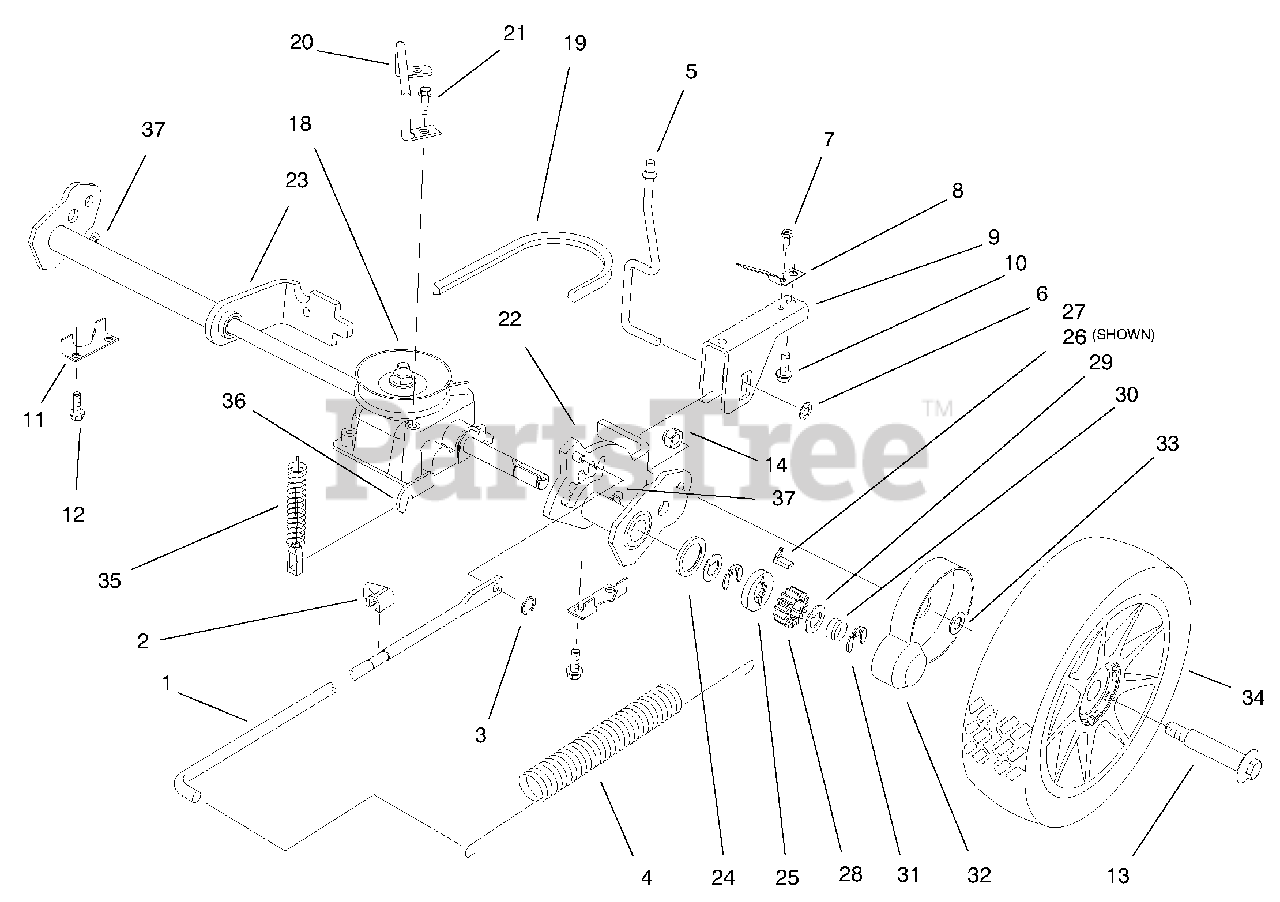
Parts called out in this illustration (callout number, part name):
1	Rod-Link
2	Indicator-HOC
3	Ring-Grip
4	Spring-Counterbalance
5	Rod-Trigger
8	Spring-Trigger Retainer
9	Saddle-HOC
11	Plate-Securing
12	Screw-HH Tap
13	Bolt-Shoulder
14	Nut-Lock
18	Gear Case Assembly
20	Retainer-Belt
21	Screw-HH Tap
22	Pivot Arm Assembly LH
23	Pivot Arm Assembly RH
24	Ring-Friction
26	Key-Rocking LH
28	Gear-Pinion
29	Washer-Thrust
30	Spring-Compression
31	Ring-Retaining
32	Cover-Wheel
33	Spacer-Wheel
34	Wheel & Tire Assembly
35	Spring-Compression
36	Bracket-Traction (Incl. with 71-9600)
37	Grease Zerk
